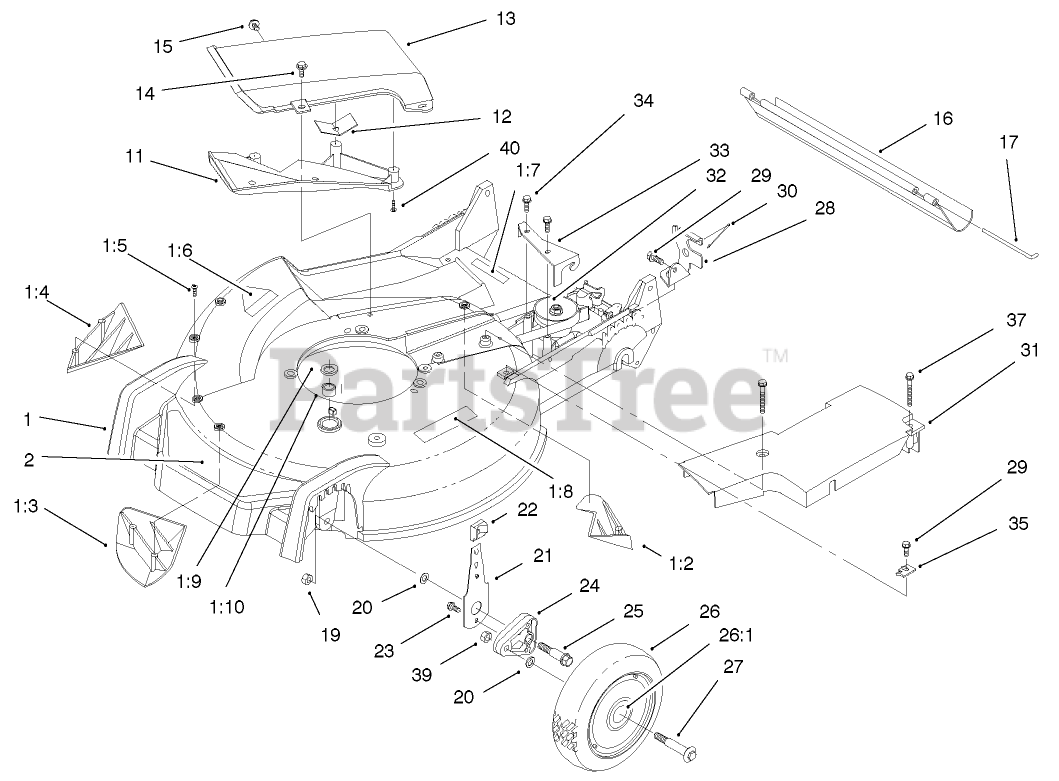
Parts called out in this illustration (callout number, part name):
1	HOUSING
1:2	KICKER-REAR
1:3	KICKER-FRONT
1:4	KICKER-RH
1:5	SCREW-PPH
1:6	DECAL-DANGER
1:7	DECAL-WARNING
1:9	WASHER
1:10	BEARING
2	DECAL-DECK
11	Deflector-Recycler
12	Guard-Cover
14	SCREW-HWH
15	SCREW AND WASHER ASM
17	ROD-SHIELD
19	NUT-LOCK
20	WASHER
21	FRONT SPRING ARM ASM
22	KNOB-ARM
23	SCREW-HWH
24	ARM-PIVOT, FRONT
25	BOLT-SHOULDER
26	WHEEL ASM
26:3	BUSHING
27	BOLT-SHOULDER
28	BRACKET-TRACTION, ADJ.
29	SCREW-HWHTF
30	RETAINER-CABLE
32	GEARCASE ASM
33	BRACKET-GUIDE, BELT
34	SCREW-HWHTF
35	CLAMP-CABLE
37	SCREW-HWH
39	LOCKNUT
40	Screw-PPH
